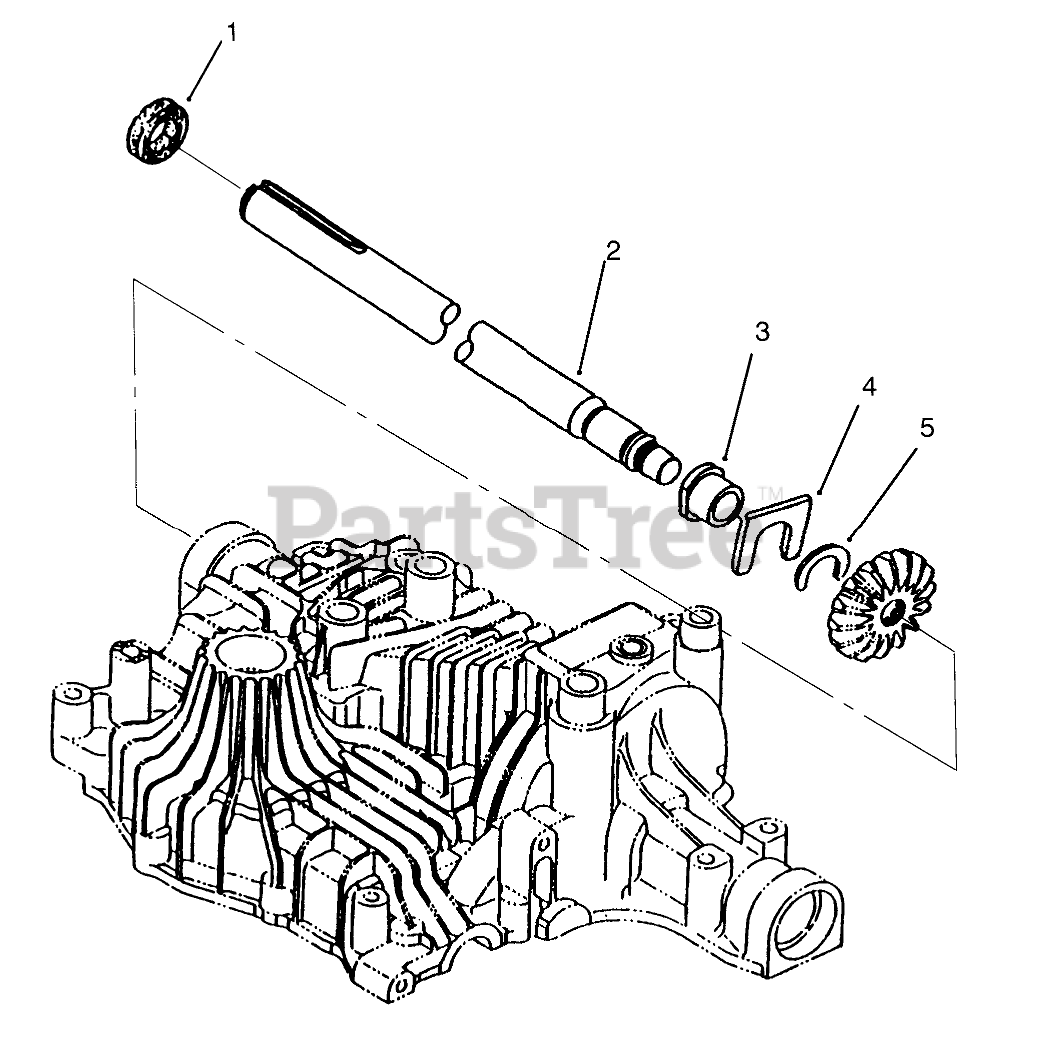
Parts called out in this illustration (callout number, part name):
2	Shaft-Axle Right
3	BUSHING
4	WASHER - THRUST
